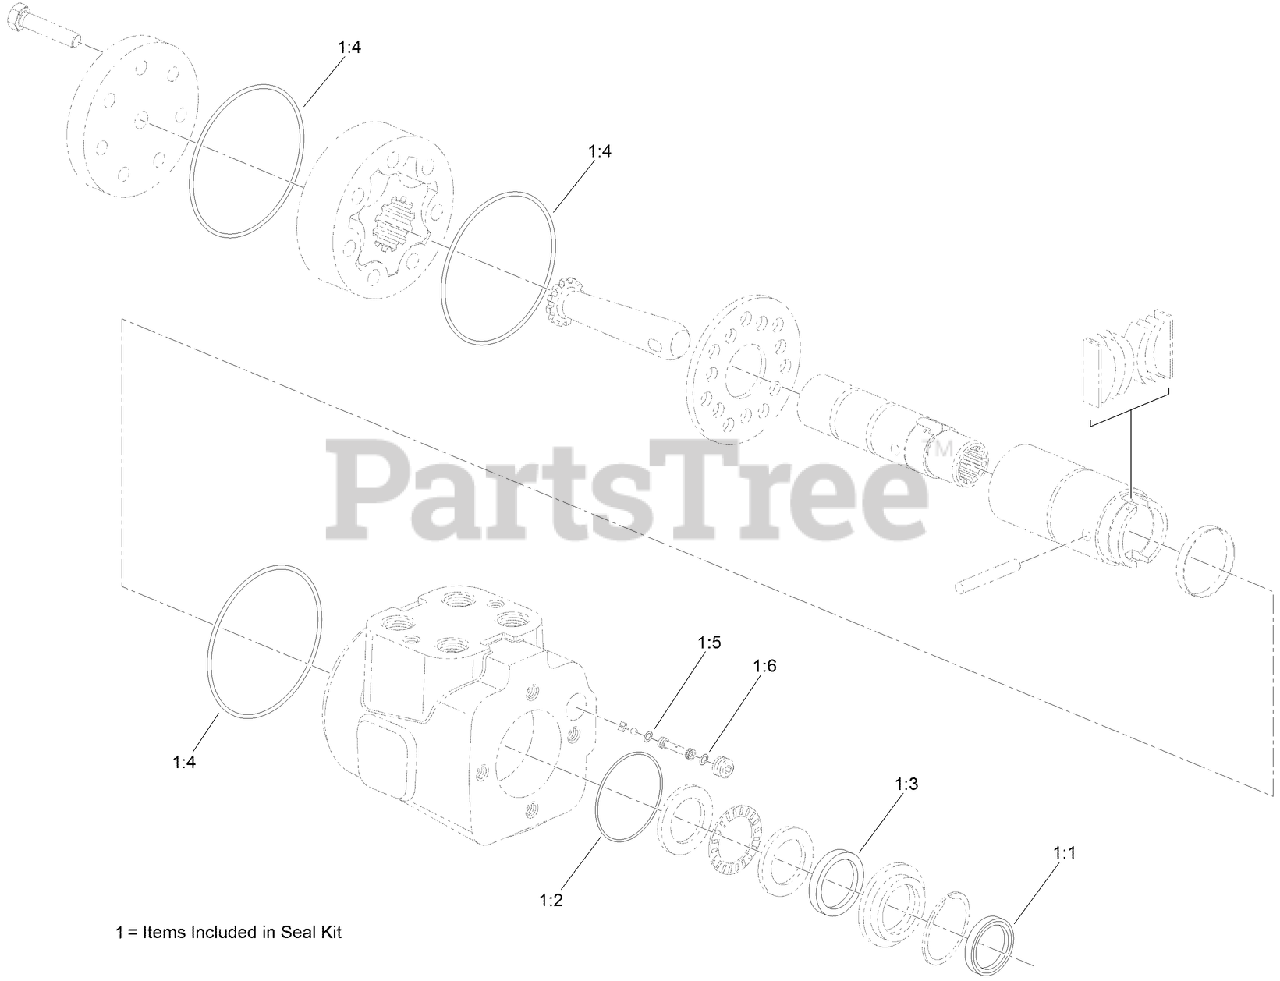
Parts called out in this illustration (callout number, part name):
1	SEAL KIT
1:1	HUB and BEARING ASM
1:2	HUB and BEARING ASM
1:3	HUB and BEARING ASM
1:4	HUB and BEARING ASM
1:5	HUB and BEARING ASM
1:6	HUB and BEARING ASM
